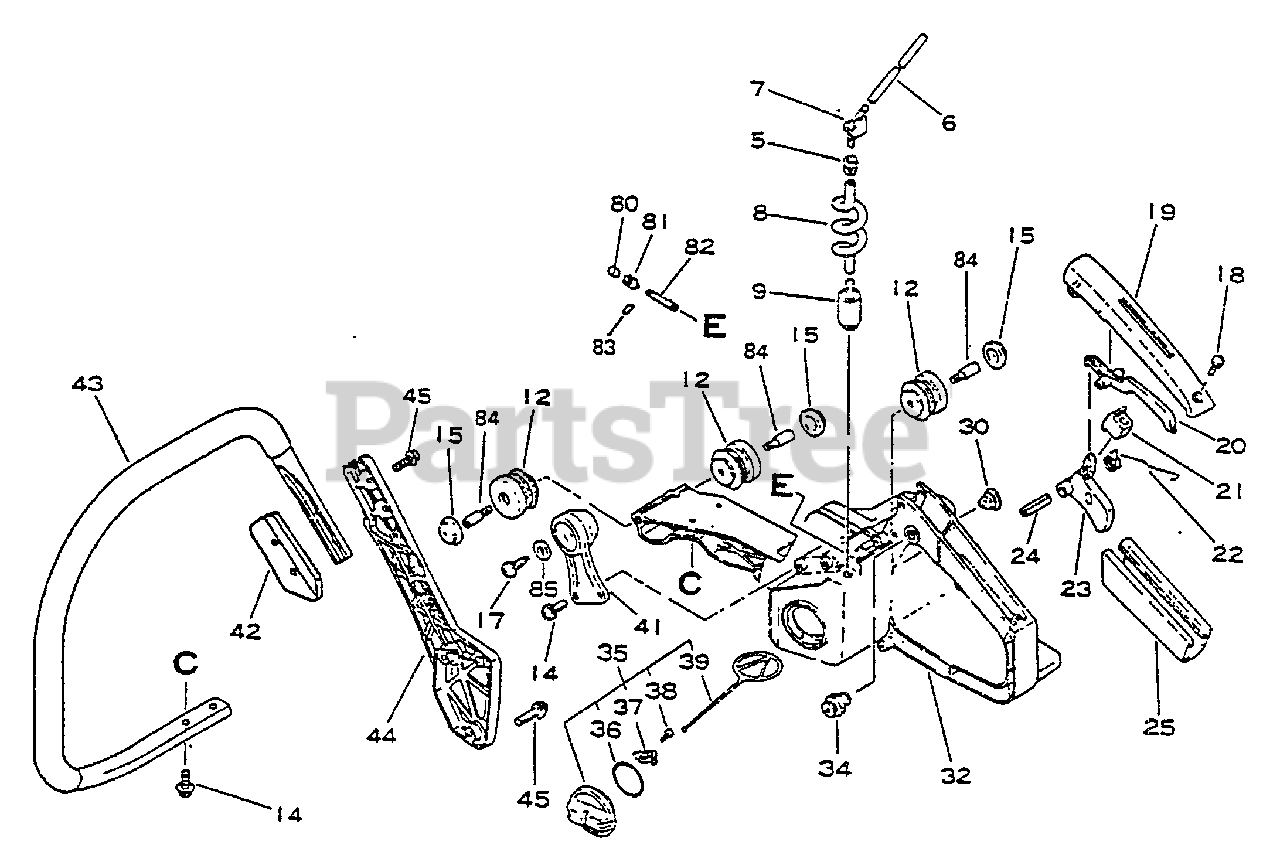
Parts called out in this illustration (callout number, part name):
5	GROMMET
6	PIPE - 3X6X100 -- BLACK
7	CONNECTOR, PIPE
8	PIPE - BLACK
9	FILTER, FUEL
13	CUSHION
14	SCREW - 5X14
15	CAP, CUSHION
18	SCREW - 4X14
19	COVER, HANDLE
20	LEVER, TRIGGER LOCKOUT
22	SPRING, TRIGGER
23	TRIGGER, THROTTLE
24	PIN - SPRING -- 5X25
25	GRIP, HANDLE
32	HANDLE - REAR
34	LOCK, THROTTLE
35	CAP ASSY
36	O-RING - 29
37	RETAINER
38	SCREW - 3X8
39	CONNECTOR, CAP
42	BRACKET, HANDLE
43	HANDLE - FRONT
44	BRACKET, HANDLE
45	SCREW - 5X20
80	VENT, FUEL TANK
81	COVER, VENT
82	PIPE - VENT
83	CLIP - 5.5
85	WASHER - 5
